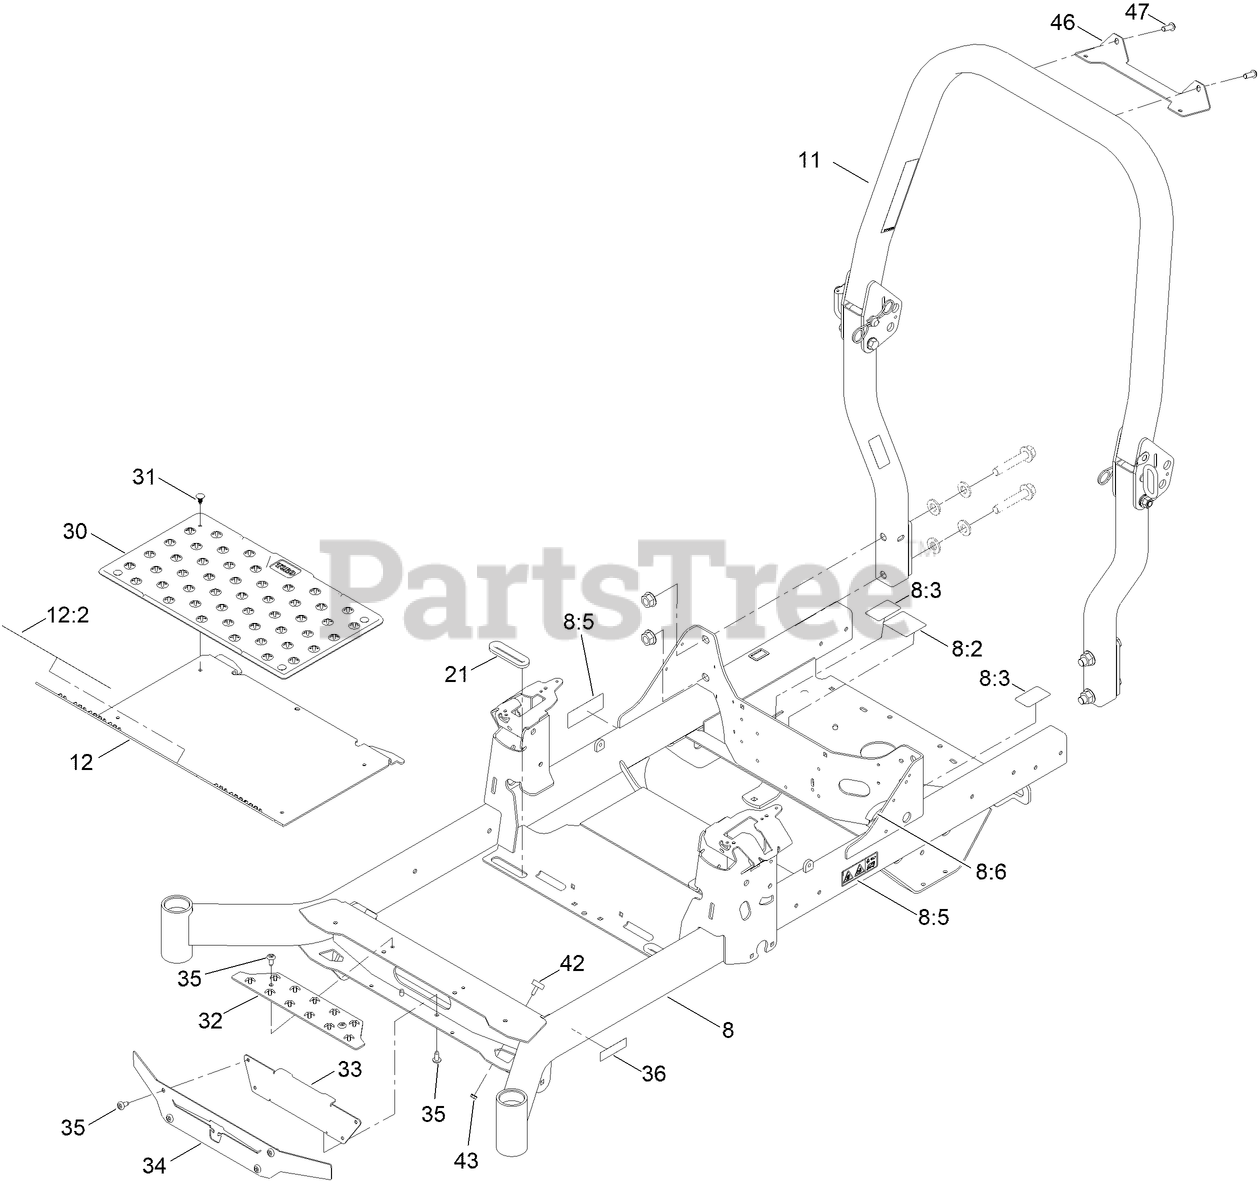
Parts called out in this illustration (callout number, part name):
8	FRAME-60 [W/DECALS]
8:2	DECAL-ROUTING, BELT
8:3	DECAL-RELEASE, DRIVE
8:5	DECAL-WARNING
8:6	STRIP-SEAL
11	ASM-ROPS
12	PAN-FLOOR ASM [SERVICE]
12:2	DECAL-DANGER
21	GROMMET-RUBBER
30	MAT-FLOOR
31	PLUG-PLASTIC
32	PLATE-STEP
33	PLATE-BACKER
34	PLATE-FASCIA
42	BUMPER-RUBBER
43	NUT-HF
46	BRACKET-LIGHT
47	SCREW-HWH
